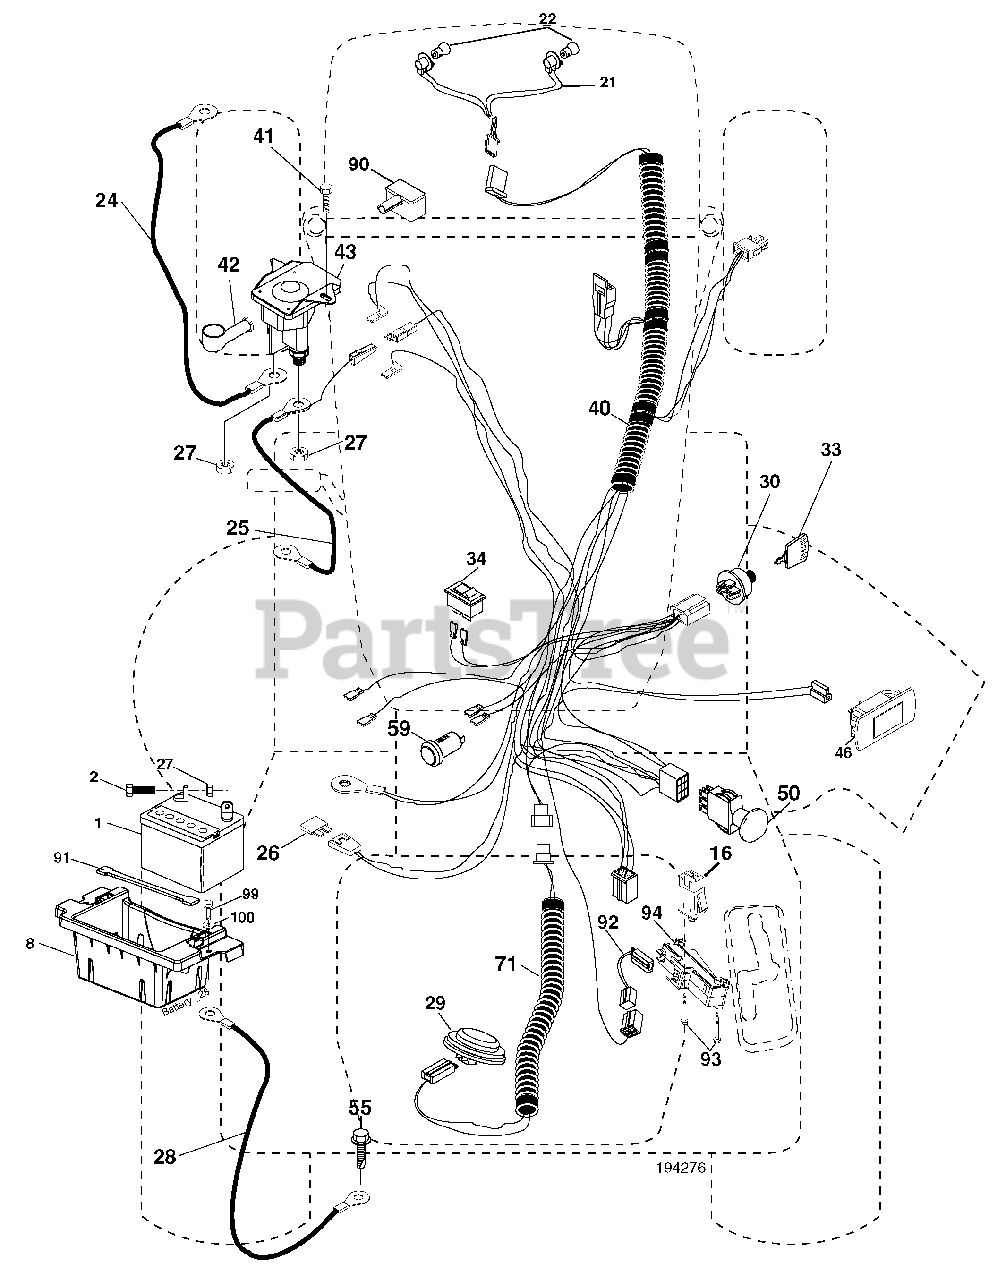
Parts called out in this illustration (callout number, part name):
1	Battery
2	Bolt Hex Hd 1/4-20 unc x 3/4
8	Battery Box
16	Switch Interlock
21	Harness Socket Light
22	Bulb, Light # 1156
24	Cable Battery
25	Cable Starter
27	Nut Keps Hex 1/4-20 unc
28	Cable Ground 21" Blk 6 Ga.
29	Switch Seat
30	Switch Ign
33	Key Ign Molded Generic
34	Switch Light/Reset
40	Harness Ign
41	Screw Thd Cut 1/4-20 x 1/2
42	Cover Terminal Red
43	Solenoid
46	Gauge Hourmeter
50	Switch PTO
55	Screw Thdrol 5/16-18 x 3/4
59	Outlet 12-Volt
71	Harness Ign. Dash
90	Cover Terminal Battery
91	Strap Battery
92	Harness Pigtail Consle ROS
93	Screw Plastite 10-14 x 2.0
94	Module Reverse ROS
99	Screw Hexwsh Thdrol 1/4-20 x 3/4
100	Washer 9/32 x 7/8 x 16 Ga.
